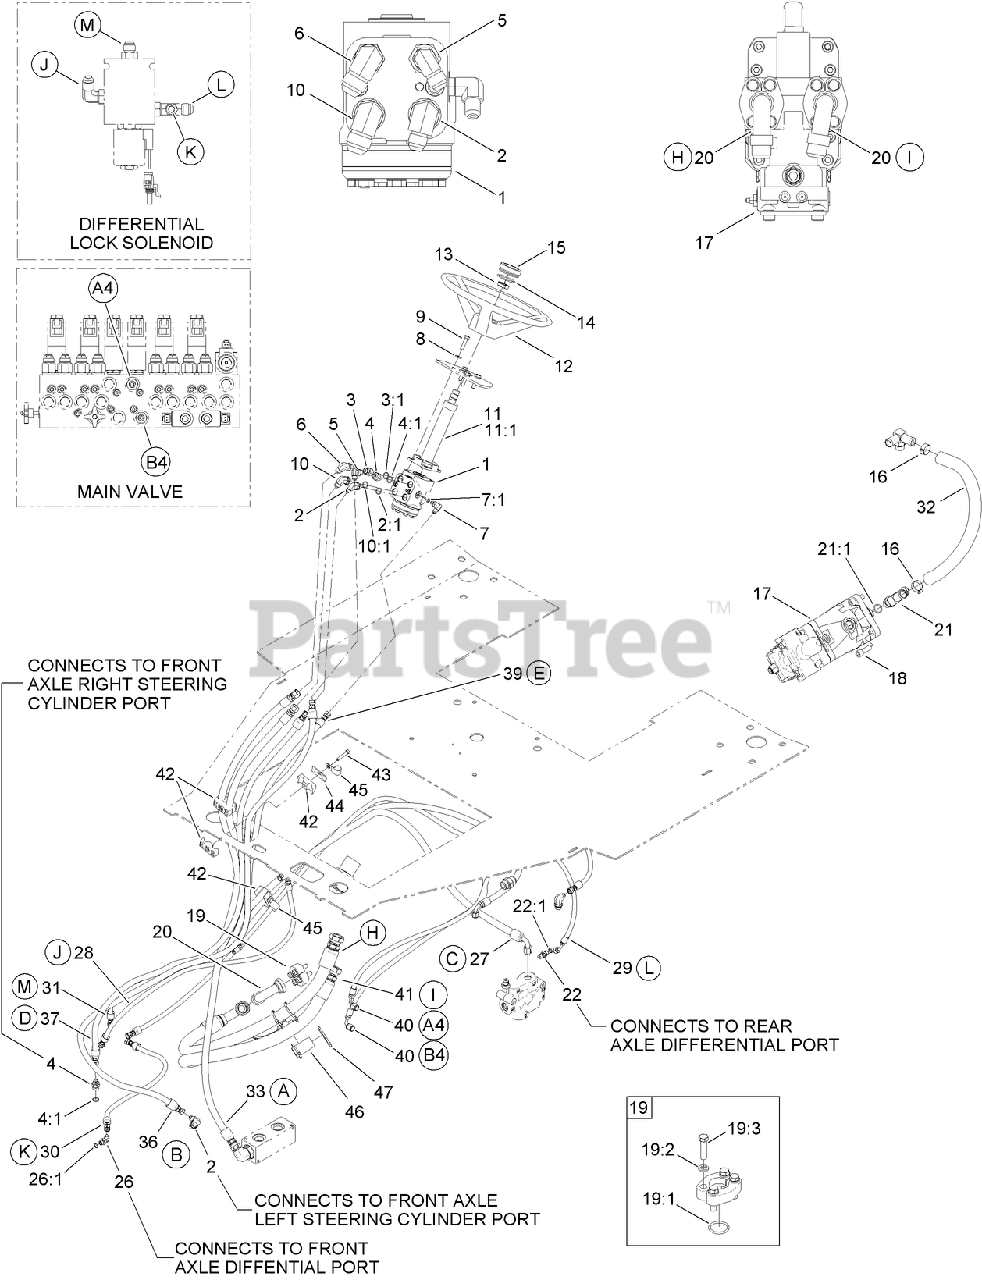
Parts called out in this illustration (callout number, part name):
1	STEERING VALVE ASM
2	FITTING-ELBOW, 90 DEG
2:1	O-RING
3	FITTING-STRAIGHT
3:1	O-RING
4	CONNECTOR
4:1	O-RING
5	ELBOW-SWIVEL, 90 DEG
6	FITTING-ELBOW, 90
7	ELBOW-90, ADJ
7:1	O-RING
8	WASHER-HARDENED
9	SCREW-HH
10	FITTING-ELBOW, 90
10:1	O-RING
11	STEERING COLUMN ASM
11:1	BOOT-RUBBER, BEARING
12	WHEEL-STEERING
15	CAP-STEERING WHEEL
16	CLAMP-HOSE
17	HYD MOTOR ASM
18	SCREW-HSH
19	HYD FLANGE KIT
19:1	O-RING
19:2	WASHER-LOCK
19:3	SCREW-HH
20	FITTING-ELBOW
21	FITTING-TEE, RUN
21:1	O-RING
22	FITTING-ELBOW, 90 DEG
22:1	O-RING
26	FITTING-ELBOW, 45 DEG
26:1	O-RING
27	HYD HOSE ASM, HP
28	HYD HOSE ASM, HP
29	HYD HOSE ASM, HP
30	HYD HOSE ASM
31	HYD HOSE ASM
33	HYD HOSE ASM, HP
36	HYD HOSE ASM, HP
37	HYD HOSE ASM
39	HYD HOSE ASM, HP
40	HYD HOSE ASM, HP
41	HYD HOSE ASM, HP
42	CLAMP-TUBE
43	SCREW-HH
44	PLATE-COVER
45	CLAMP-R
46	PROTECTOR-HOSE
47	TIE-CABLE
